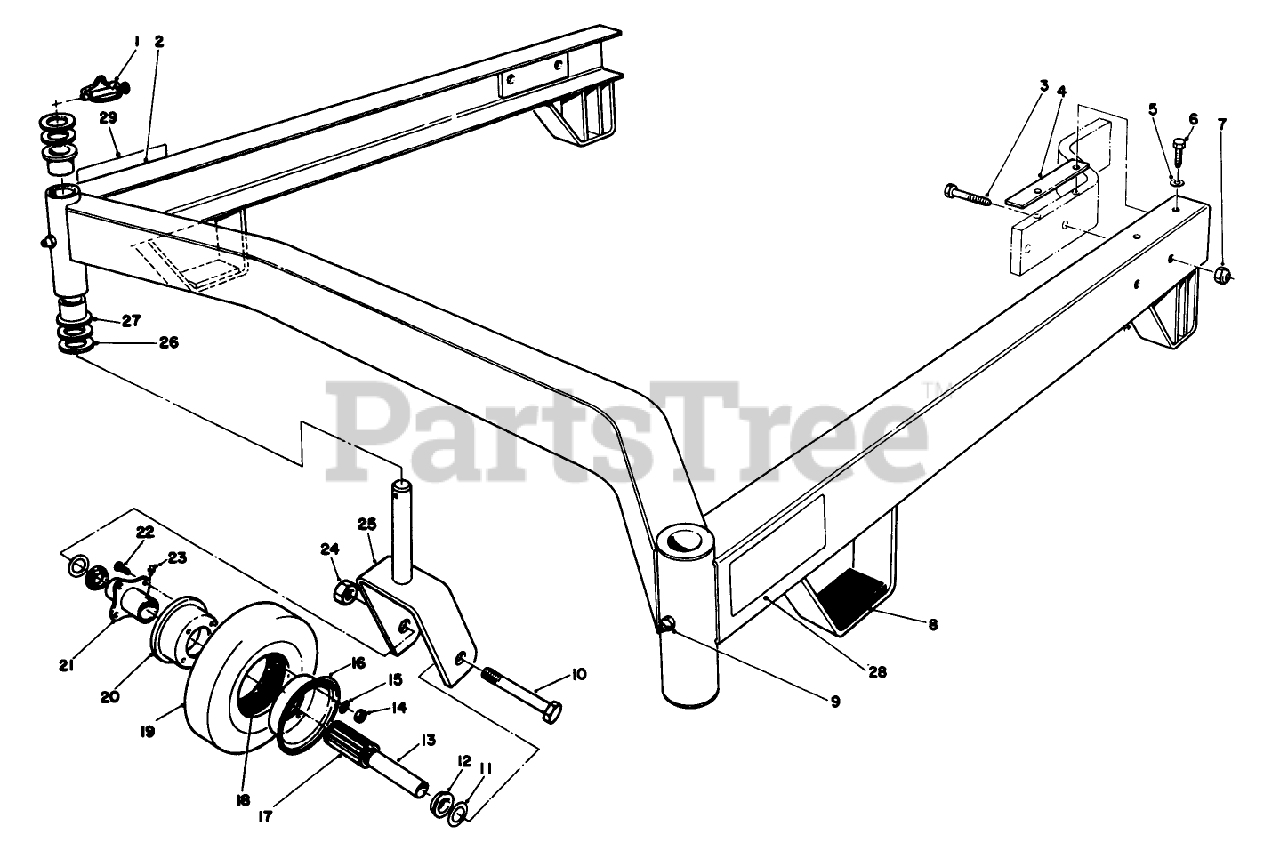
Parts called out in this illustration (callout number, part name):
1	PIN-LYNCH
3	SCREW-HH
4	SHIM-CARRIER
5	WASHER-FLAT
6	SCREW W/PATCH
7	NUT-LOCK, CONE
9	FITTING-GREASE
10	SCREW-HH
11	WASHER-FLAT
12	BEARING-OUTSIDE
13	SPANNER-TIRE
14	NUT-HEX
15	SCREW-HH
16	MALE WHEEL HALF
17	BEARING-ROLLER
18	TUBE-INNER (W/VALVE)
20	FEMALE WHEEL HALF
21	HUB-CENTER
22	WHEEL BOLT
23	FITTING-GREASE
24	NUT-HEX
26	WASHER-THRUST
28	DECAL-HOC, RH
29	DECAL-HOC, LH
